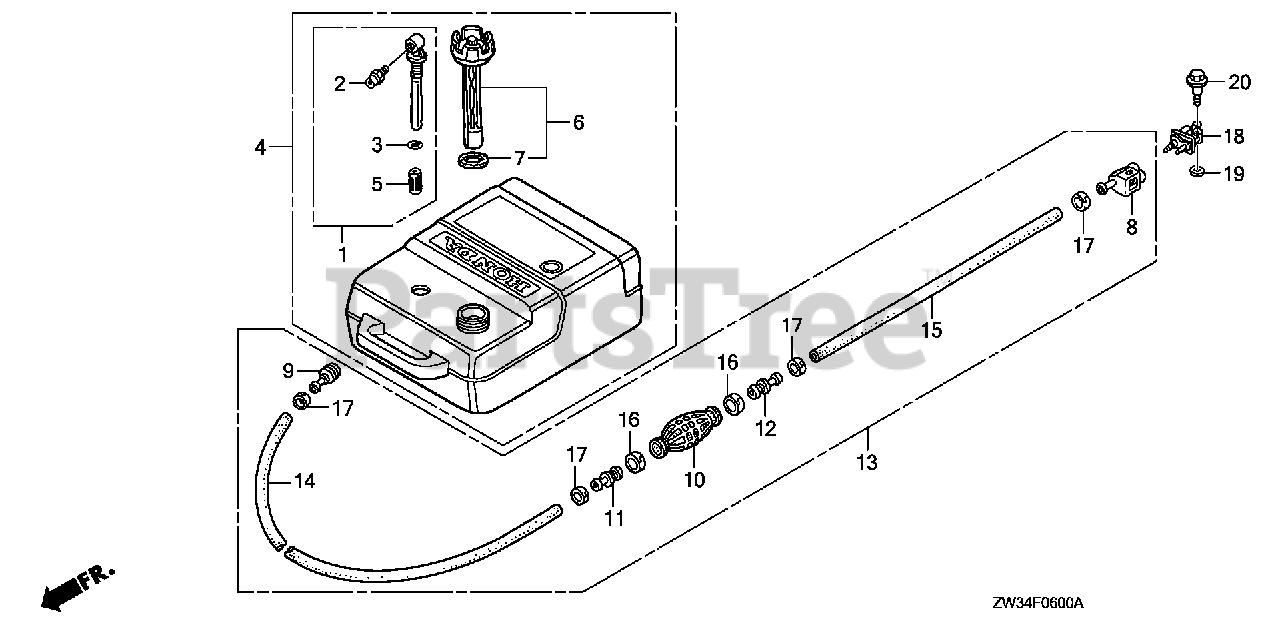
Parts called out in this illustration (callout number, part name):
8	CONNECTOR ASSY., FUEL (A)
9	CONNECTOR, FUEL
10	BULB, PRIMER
11	VALVE, IN.
12	VALVE, OUTLET
13	TUBE ASSY., FUEL
14	TUBE, FUEL LONG (7.3X2000)
15	TUBE, FUEL SHORT (6.3X500)
16	BAND, TUBE CLIP (20MM)
17	BAND, TUBE CLIP (12.5MM)
18	CONNECTOR ASSY., FUEL (B)
19	WASHER, PIVOT
20	BOLT, SPECIAL (6X22) (CT200)
